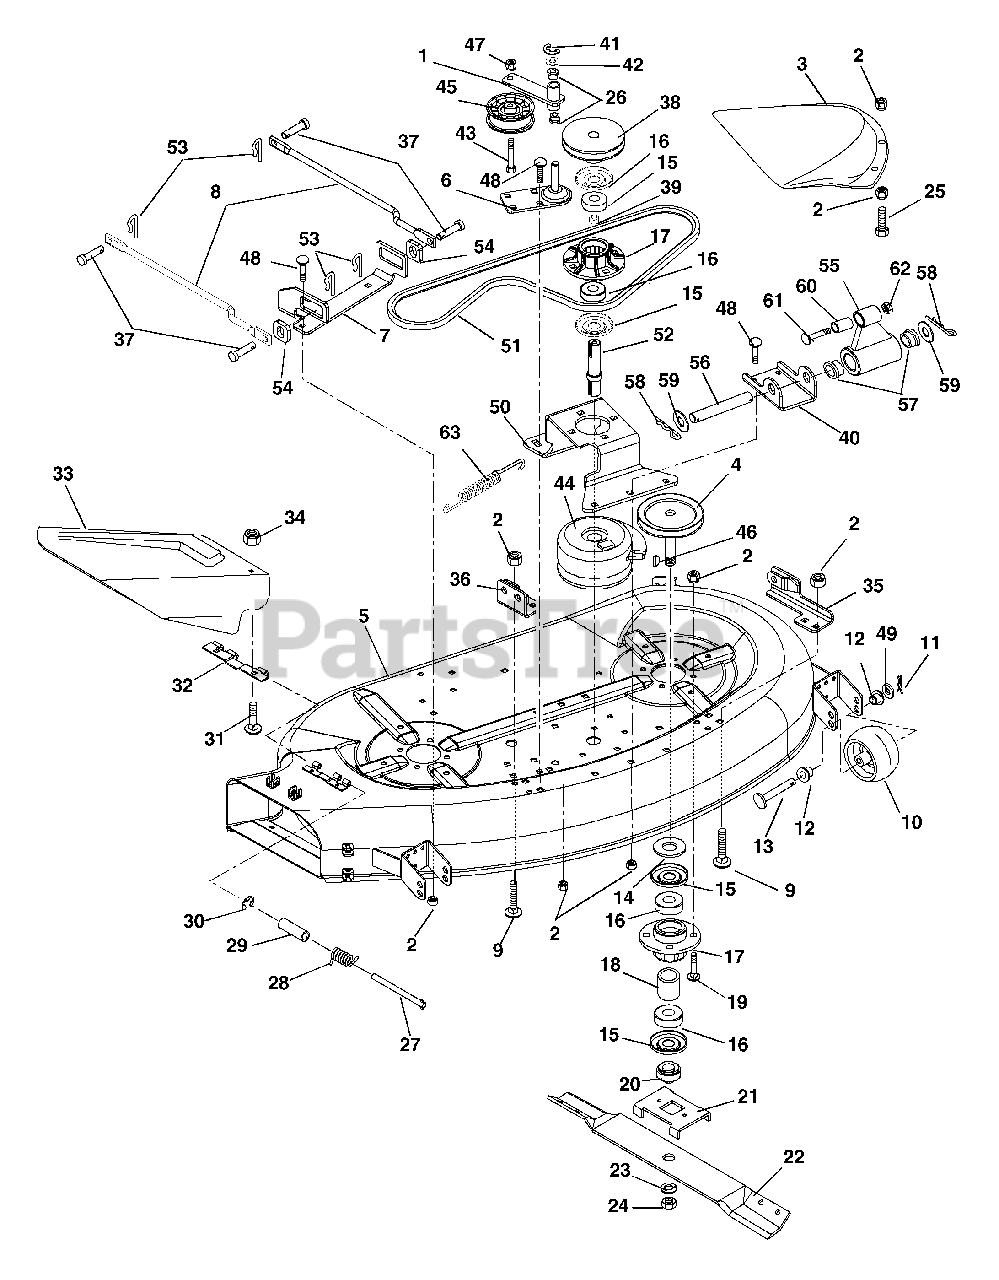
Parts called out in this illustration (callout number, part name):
1	WLDMT-IDLER
2	NUT-LK-TOP-FLG .38-16 BLKZC
4	L. SPINDLE SHEAVE
5	WLDMT - 40" DECK RAW
6	BKT-IDLER MOUNT
7	BRKT, REAR HANGER (40" DECK)
8	LINK-STABILIZER 40" DECK BLK
9	BLT-RDHDSQNK .38-16X.75 G5BZ
11	PIN-HAIR INT .08X.18X1.18 YWZC
12	BSHG-FLG .372X.500X.312X.625NY
13	PIN-CLEV .371X3.25 YWZC
14	WSHR-FL-STL .755X1.25X.125 YZ
15	BEARING SLINGER
16	BRG-BALL .750X1.781X.61
17	SPINDLE HOUSING
18	SPACER .753X1.000X1.140
19	@BLT-RDHDSQNK .38-16X1.00 G5YZ
20	RETAINER HUB
21	BLADE TRAY 48
23	@WSHR-LK .75X.188 REG YWZC
24	NUT-JAM .75-10 YWZC
25	@BLT-HEX .38-16X1.00 GR5 YWZC
26	BSHG-FLG.500X.625X.312X.750NY
28	SG-TORS .090X.37X.63
29	BSHG-SLV .334 X .502 X 1.437
30	RG-RTNG-EXT .312X.025
31	BLT-RDHDSQSHNK.25-20X.50 YWZC
32	HINGE PLATE
33	40IN. CHUTE DEFLECTOR
34	@NUT-SPNLK-FLG .25-20 YWZC
35	BKT-DECK LINK (LH)
36	WLDMT DECK LINK BKT (RH)
37	PIN-CLEV .494X1.00 BLKZC
38	PULLEY, 40" DECK INPUT
39	SPACER .753X1.000X1.140
40	BRKT, FRONT HANGER
41	RG-RTNG-EXT .500X.042 (E)
42	WSHR-FL-STL .505X.880X.072 YWZ
43	@BLT-HEX .38-16X1.50 GR5 YWZC
44	ELECTRIC CLUTCH/BRAKE (3.4AMP)
45	IDLER-FLAT 3.00X.38
46	KEY-WDRF .188X.625X.31 SAE9MOD
47	@NUT-SPNLK-FLG .375-16 YWZC
48	@BLT-RDHDSQNK .31-18X.75 G5YZ
49	BLT-RDHDSQNK .31-18X1.0 SHTYZ
50	BKT SPINDLE HSG MOUNT
51	V-BELT, HA-RAW EDGE
52	SHAFT, 40" DECK INPUT
53	CLIP, SPRING
54	SLIDER, HANGER BRKT
55	LINK, FRONT LIFT (40" DECK)
56	PIVOT, FRONT LIFT LOWER
57	BUSHING-1"X.75"X1"
58	PIN, HAIR #6
59	WSHR-FL-STL .700X1.47X.134 YWZ
60	BSHG-SLV .500X.750X1.560
61	BLT-RDHDSQSHNK .50-13X2.75 YZ
62	NUT-LK-CTR-JAM .50-13 YWZC(ND)
63	SG-TENS .095X.500X5.5 WLD60 YZ
